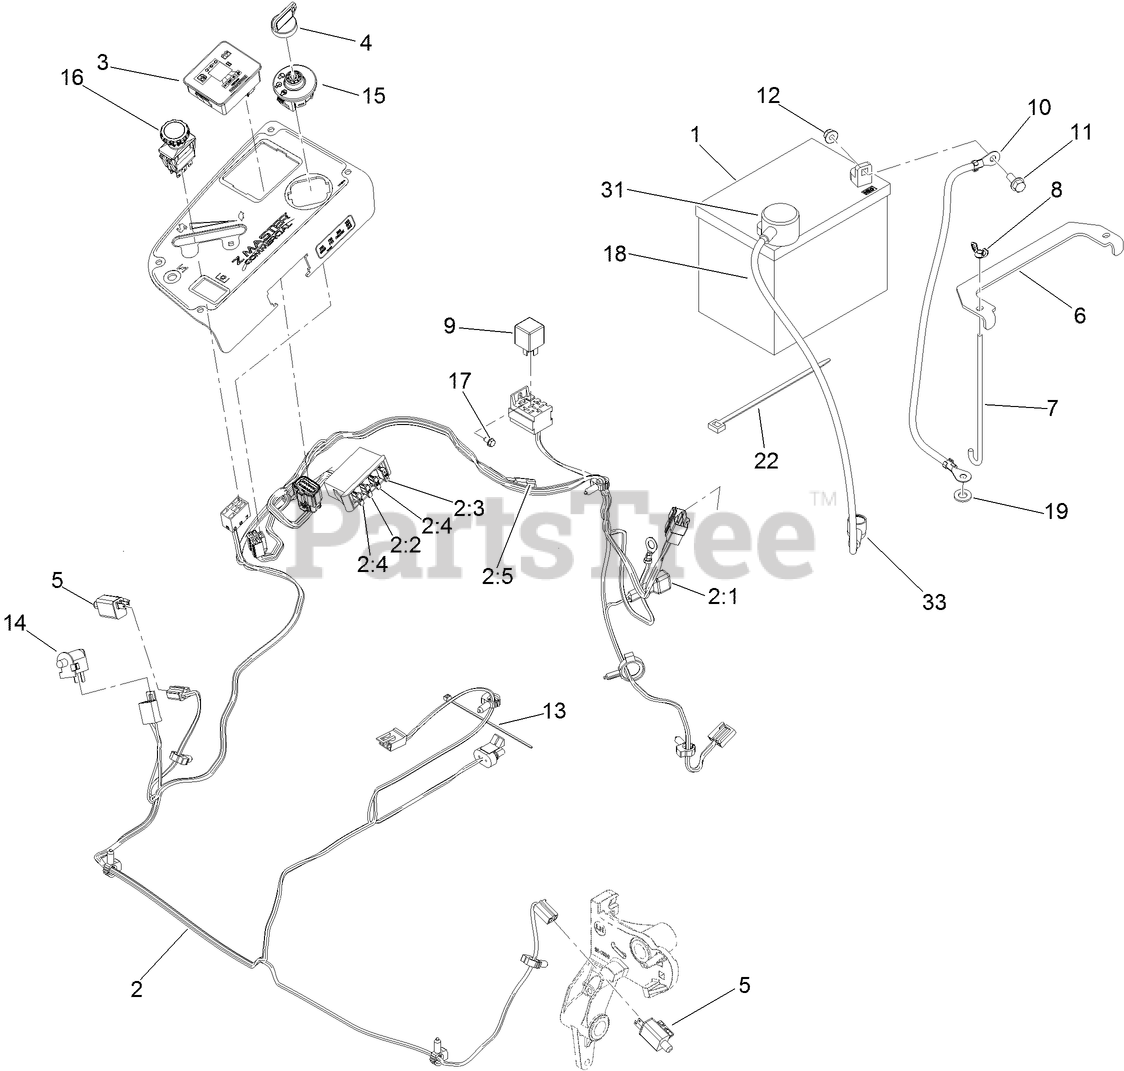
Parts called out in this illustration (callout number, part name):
1	BATTERY
2	HARNESS-WIRE, MAIN
2:2	FUSE-BLADE, 10 AMP
2:3	FUSE-BLADE, 15 AMP
2:4	FUSE-BLADE, 25 AMP
2:5	CAP-PLUG
3	FUEL/HOUR METER ASM
4	KEY-IGNITION
5	SWITCH
6	STRAP-TIE DOWN, BATTERY
7	BOLT-HOLDDOWN
8	WINGNUT
10	CABLE-BATTERY, NEGATIVE
11	SCREW-HHF
12	NUT-HF, NI
13	TIE-CABLE
14	SWITCH-BAIL
15	SWITCH-IGNITION
16	SWITCH-PTO, 10 AMP
17	SCREW-HWH
18	CABLE-BATTERY, POSITIVE
19	WASHER-FLAT
22	TIE-PLASTIC
31	INSULATOR-BATTERY
33	INSULATOR-SOLENOID
